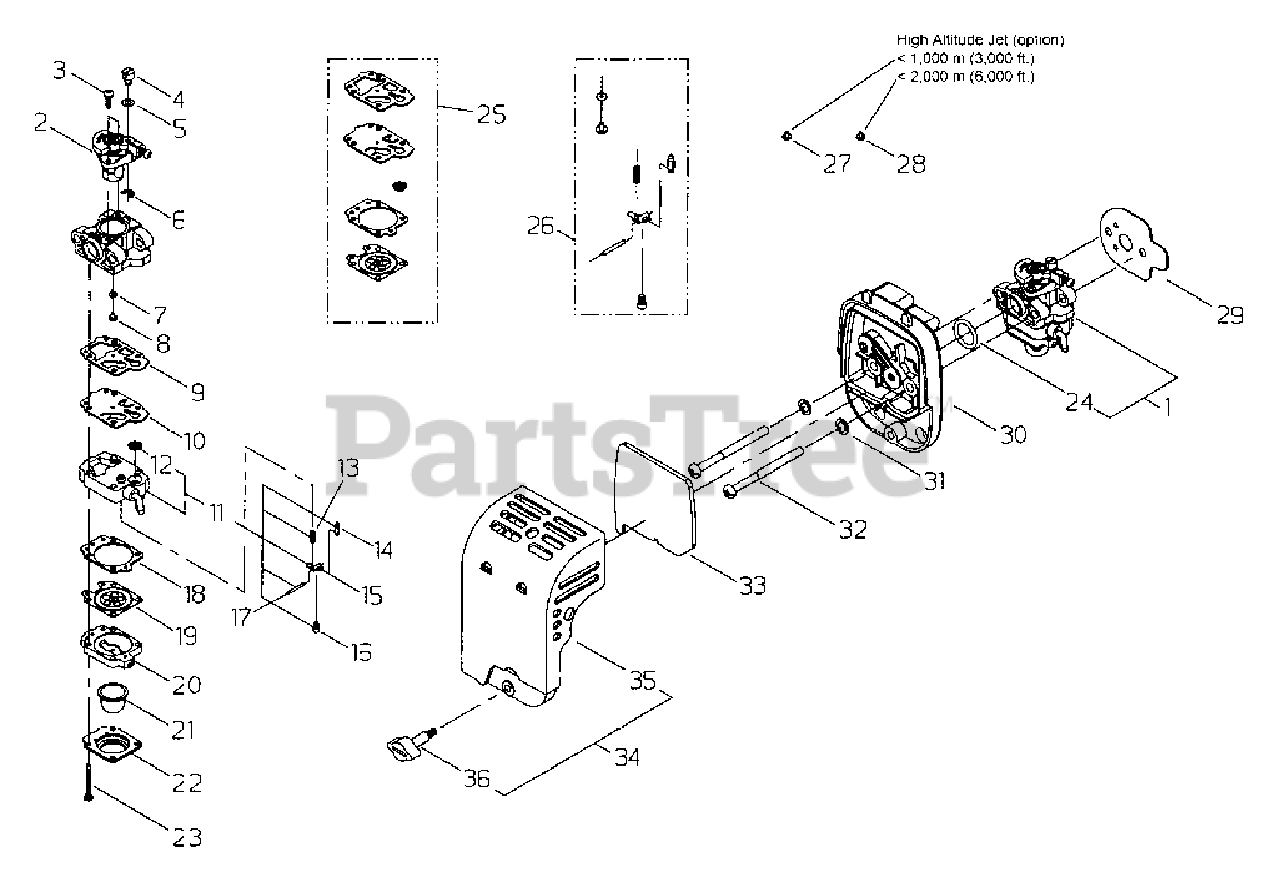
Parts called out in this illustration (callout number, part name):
1	CARBURETOR
2	VALVE ASSY, THROTTLE
3	SCREW, THROTTLE COLLAR
4	SWIVEL
5	WASHER
6	E-RING
7	GASKET, PUMP
8	JET, MAIN
9	GASKET, PUMP
10	DIAPHRAGM, PUMP
11	BODY ASSY, PUMP
12	SCREEN, FUEL INLET
13	SPRING, METERING LEVER
14	VALVE, INLET NEEDLE
15	LEVER, METERING
16	SCREW
17	PIN, METERING LEVER
18	GASKET, METERING DIAPHRAGM
19	DIAPHRAGM, METERING
20	BODY ASSY, PURGE
21	BULB, PURGE
22	RETAINER, PURGE BULB
23	SCREW
24	O-RING 15
25	GASKET / DIAPHRAGM KIT
26	VALVE KIT, INLET NEEDLE
27	JET, MAIN
28	JET, MAIN
29	GASKET, INTAKE
30	CASE ASSY, AIR FILTER
31	WASHER 5 MM
32	SCREW M5×60
33	FILTER, AIR
34	COVER ASSY, AIR FILTER
35	COVER, AIR FILTER
36	THUMBSCREW M5
